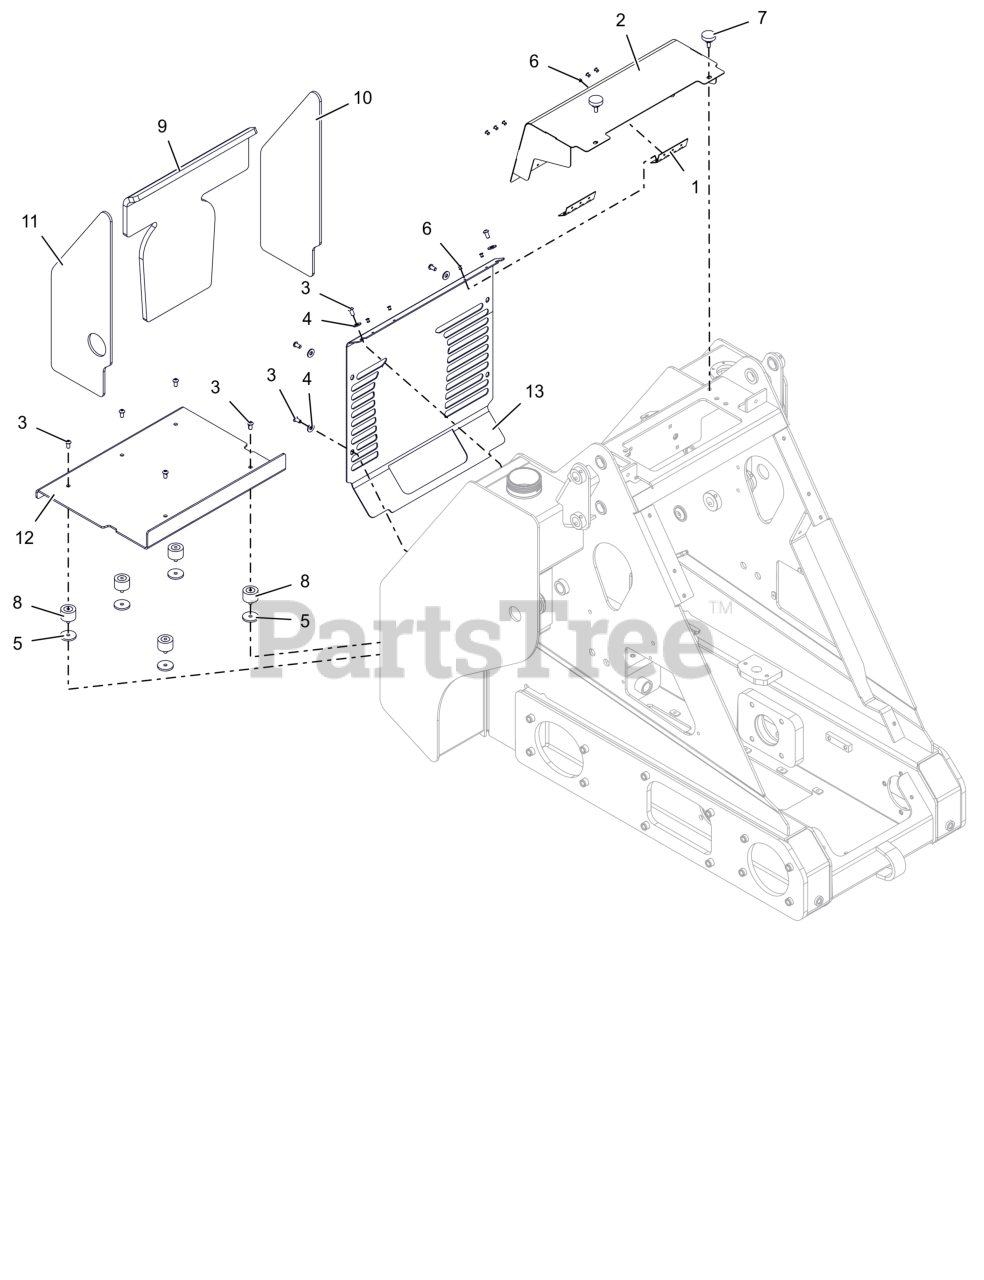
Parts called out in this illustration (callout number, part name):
2	COVER, CMBNR - W/SAFETY DECALS
3	SCR,BTNHD .31-18X.625 ZCC
4	WSHR,FLT .375X.875X.083 ZCC
5	WSHR, FLT .328X1.56X.175 ZCC
6	RVT-POP .187X.402 DOME ST
7	KNOB, W/ STUD 5/16" 18 X 3/4
8	ISOLATOR, RUBBER
9	PAD, LOWER OPERATOR SHIELD
10	PAD, OIL TANK LHS
11	PAD, FUEL TANK RHS
12	PLATFORM, OPERATOR (BLACK)
13	GUARD, LOWER - OPERATOR (BLACK)
